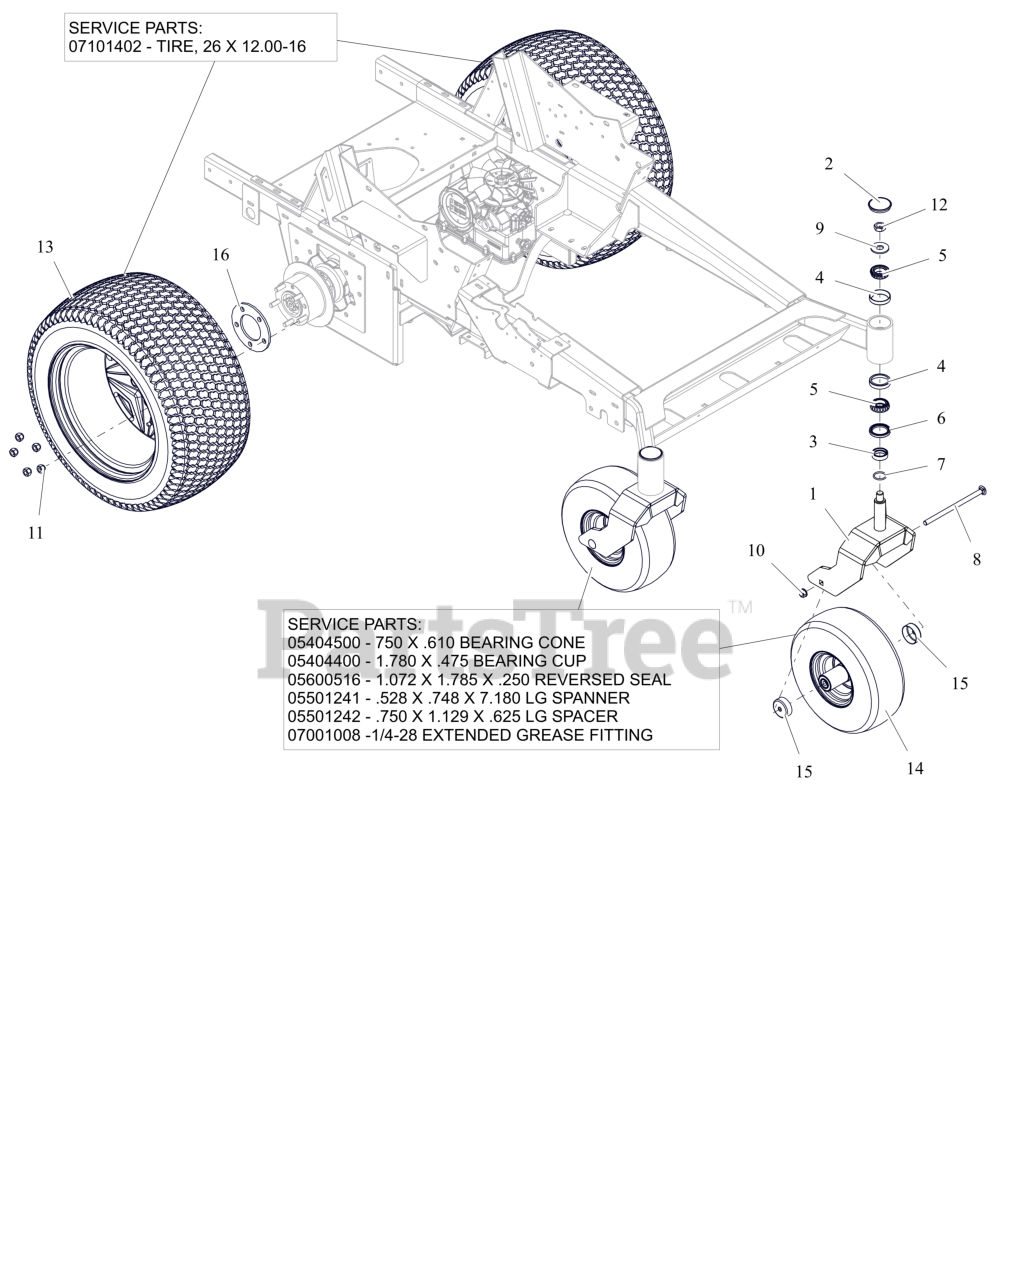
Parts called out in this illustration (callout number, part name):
1	WLDMT, CASTER FORK (RED)
2	CAP, DUST
3	SPCR, FRONT CASTER FORK
4	BRG-CUP 2.328X.465
5	BRG-CONE 1.25X.66
6	SEAL, OIL 1.75 X 2.332 X .312
8	BTL,RHSN .500-13 X 9 G5 ZCC
9	WSHR-FL-STL 0.812X2X0.148 ZCC
10	NUT-LK-CTR-FLG .500-13 GG ZCC
11	NUT, WHEEL .50-20 ZCC
12	NUT, JAM-TOPLOCK .750-16 ZCC
13	ASM, WHEEL /TIRE 26 X 12.00-16
13	TIRE, 26 X 12.00-16
14	ASM, TIRE/WHEEL 15 X 6.00-6 SEMI
14	BRG-CONE .750X.61
14	BRG-CUP 1.781X.475
14	SEAL,1.072X1.785X.250 REVERSED
14	SPANNER, .528X.748X7.18 LG
14	SPACER, .750X1.129X.625 LG
14	GREASE FITTING 1/4-28 EXTENDED
15	SHIELD, WHEEL BEARING
16	SPCR, PT600 WHEEL (BLACK)
